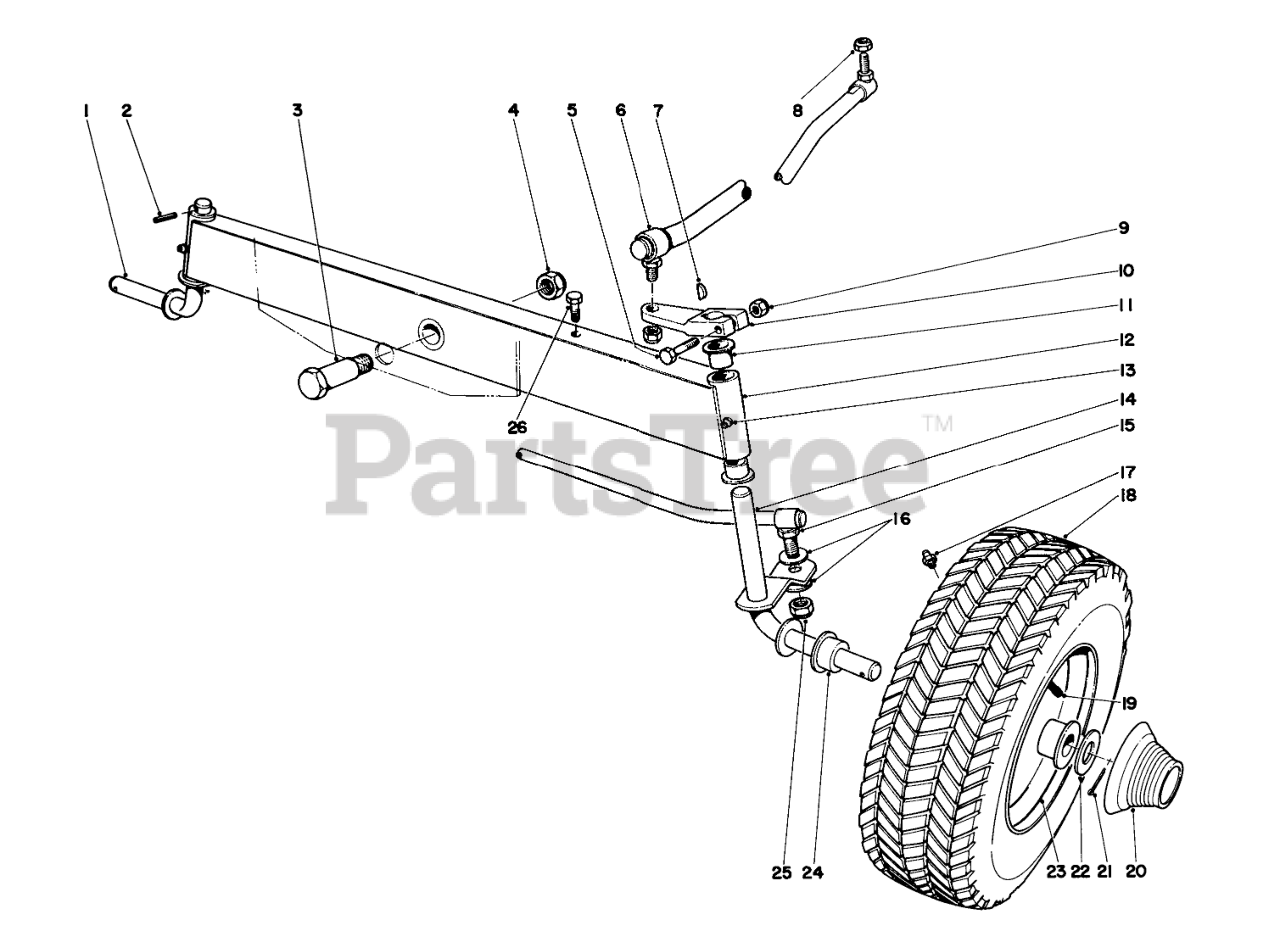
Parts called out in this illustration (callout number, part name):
1	Spindle
2	PIN-SPRING
3	Shoulder Bolt
4	1/2-13 CONELOCK NUT
5	SCREW-HH
6	Drag Link
7	KEY-WOODRUFF
8	Nut
9	NUT-LOCK, CONE
10	Arm Drag Link
11	3/4IDX1LG FLANGE BSHG
12	Front Axle (Incl. Ref. No. 11)
13	GREASE FITTING
14	Spindle L.H.
15	Tie Rod
16	WASHER
17	FITTING-GREASE
18	Tire
19	STEM-VALVE
20	FRONT HUB CAP
21	PIN-COTTER
22	Washer
24	Bushing
25	Nut
26	SCREW-HH, TAP
